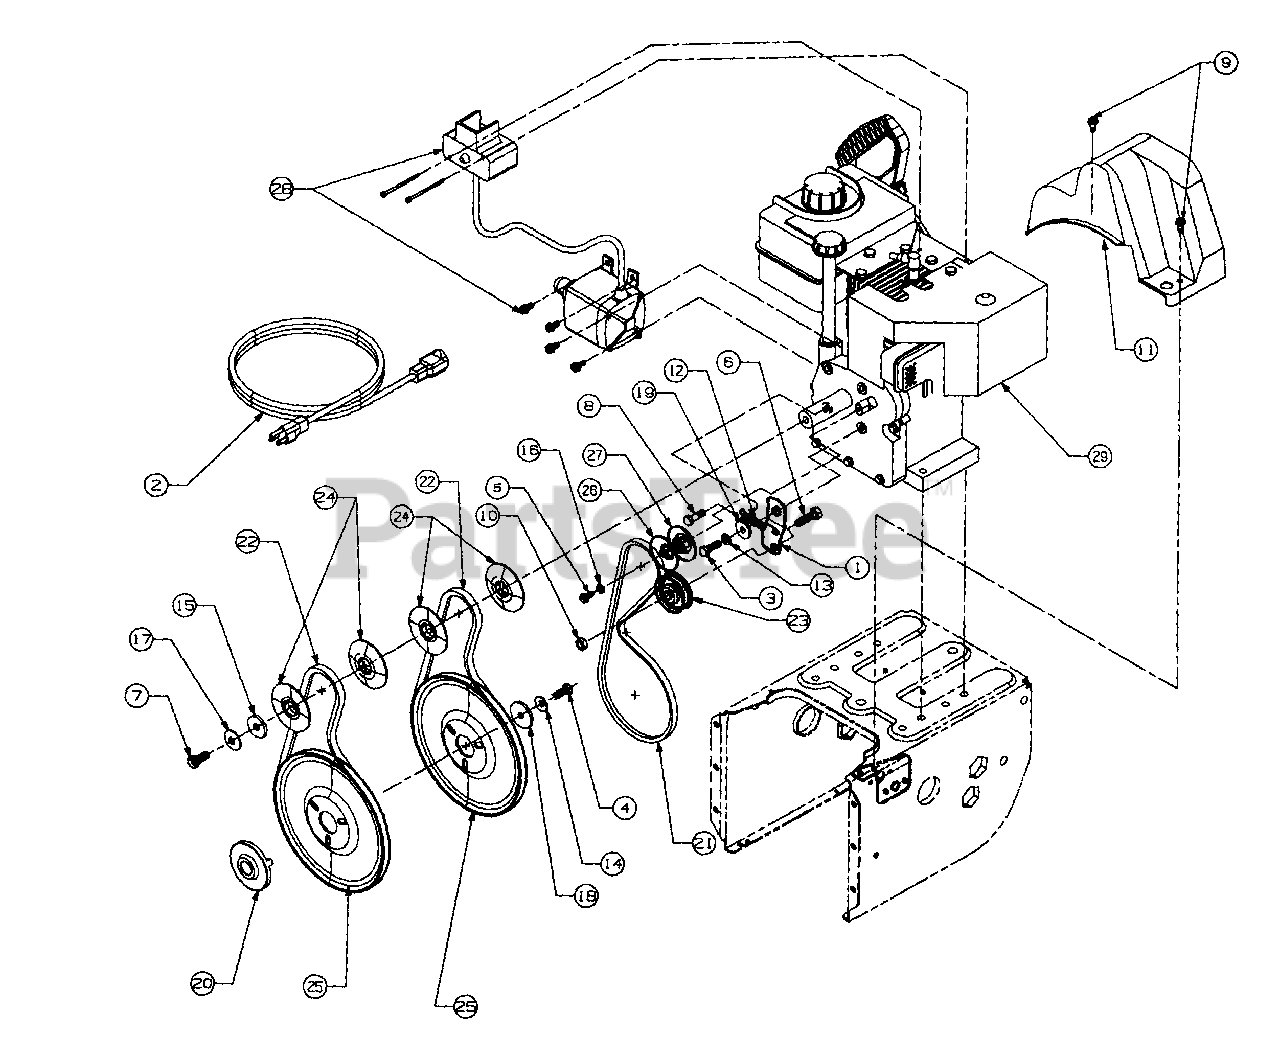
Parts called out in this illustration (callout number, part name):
3	Screw
4	Screw
5	Screw
6	Screw
7	Screw
8	Screw
9	Screw
10	Nut, Hex
11	Belt Cover
12	Spring
13	Washer - Lock
14	Washer - Bell
15	Flat Washer
16	Washer - Lock
17	Washer
18	Washer
19	Shoulder Spacer
20	Pulley Adapter
21	V-Belt
22	V-Belt
23	Idler, Flat
24	Pulley, Half
25	Pulley, Auger
26	Pulley, Half
27	Pulley, Half
28	Starter
29	Engine
